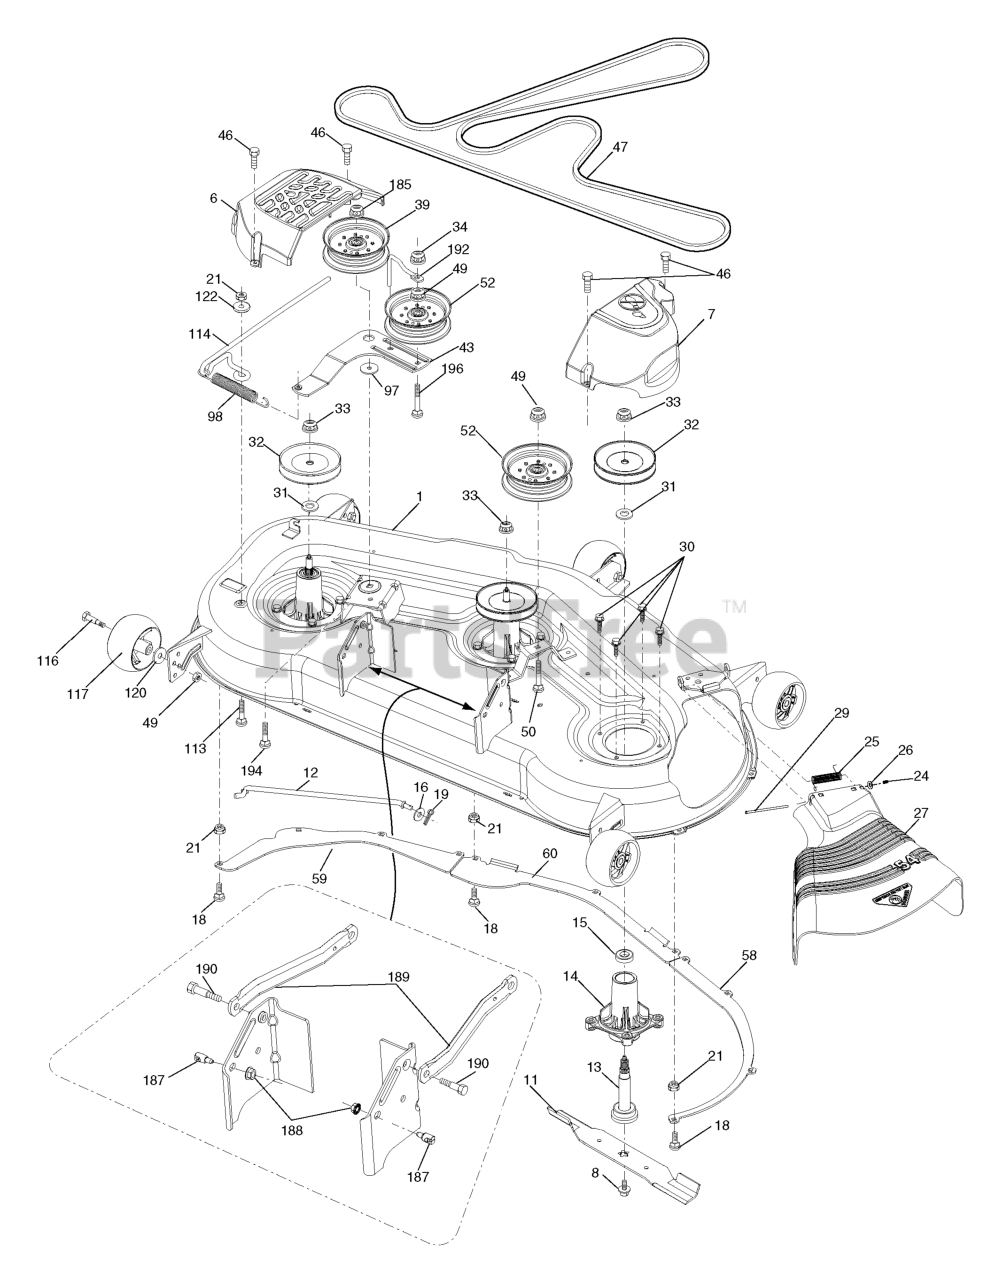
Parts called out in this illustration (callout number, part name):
1	DECK.WELDMENT.54"MS418
6	COVER.MANDREL.LH.54"20
7	COVER.MANDREL.RH.54.20
8	BOLT 7/16 ASM BLADE
11	BLADE.BAGGING.54"
11	54" MULCH BLADE
11	Blade Hi-Lift
12	ROD.ANTI.SWAY.48/54"TE
13	SHAFT ASM MANDREL
14	RP.HOUSING.MANDREL.4PT.
16	WASHER
18	BOLT
19	PIN.COTTER.5/16.BOW TI
20	BAFFLE, VORTEX MWR
21	LOCKNUT
24	CAP-SLEEVE LT
25	SPRING, TORSION
26	NUT PUSH M
27	DEFLECTOR
29	ROD.HINGE
30	SCREW, WASHER HEAD
31	WASHER.SPACER.MANDREL
32	PULLEY MANDREL
33	NUT.FLANGE.LOCK.TOP
39	PULLEY.IDLER.MWR.STATI.LH
43	ARM.IDLER
46	SCREW.1/4-20X5/8
47	RP.BELT.DRIVE.54."2006
49	NUT LOCK FLG 3/8-16 UNC
50	BOLT
52	PULLEY.IDLER.2006
58	BAFFLE.RIGHT.54"
59	BAFFLE.LEFT.54"
60	BAFFLE CENTER 54" MOWER
98	SPRING, DECK DRIVE
113	BOLT CRT
114	ROD TENSION RELIEF
116	BOLT.SHOULDER.3/8-16X3-5/8.
117	RP WHEEL. GUAGE RALLY
120	WASHER
122	BUSHING.RELIEF.TENSION
185	NUT.LOCK.FLANGE.7/16
187	STUD.FASTNER.W/ANTI-ROTATE
188	NUT LOCK HEX FLANGE 5/16-18
189	ARM.SUSPENSION.MOWER
190	BOLT.SHOULDER
192	KEEPER.BELT.IDLER.54"T
194	BOLT.CARR.SQNK.7/16
196	BOLT
